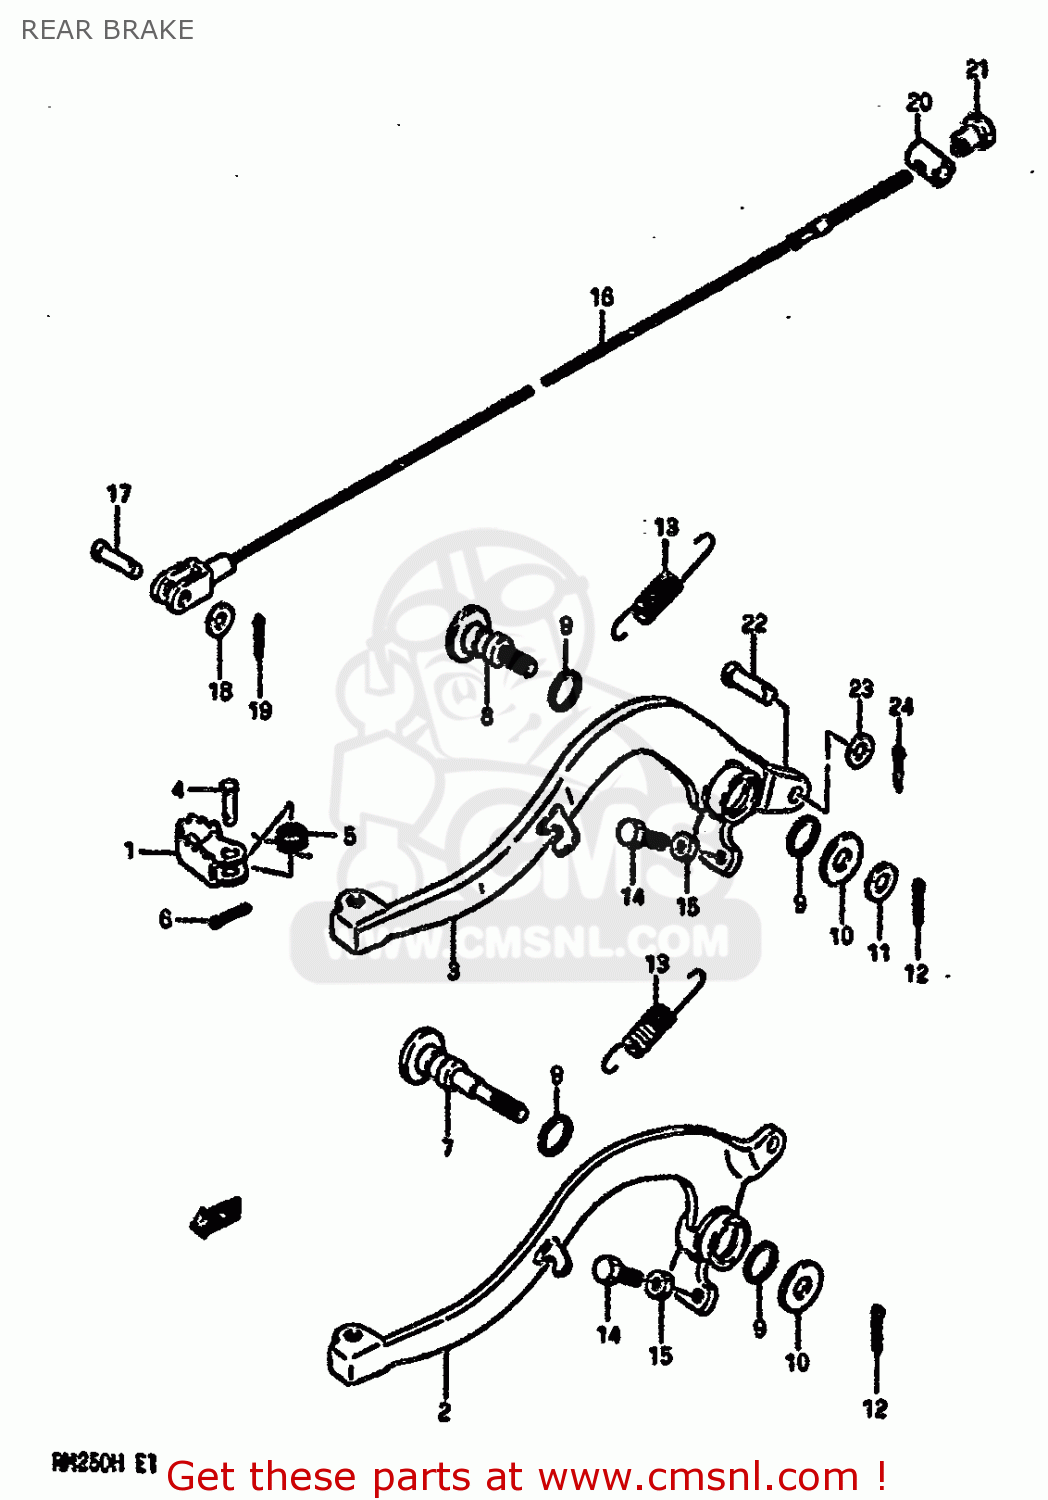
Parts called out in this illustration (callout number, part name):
1	PEDAL,BRAKE
2	ARM COMP,BRAKE PEDAL
3	ARM,BRAKE PEDAL
4	PIN
5	SPRING
6	PIN
7	SHAFT,BRAKE PEDAL
8	SHAFT,BRAKE PEDAL
9	O-RING,BOSS
10	WASHER
11	WASHER
12	PIN 20X20
13	SPRING BRAKE PEDAL
14	BOLT
15	NUT
16	CABLE,RR BRAKE
17	PIN(L:17.5)
18	WASHER
19	PIN 20X20
20	PIN
21	NUT (6MM)
22	PIN(8X20)
23	WASHER(8.5X13X1.6)
24	PIN
